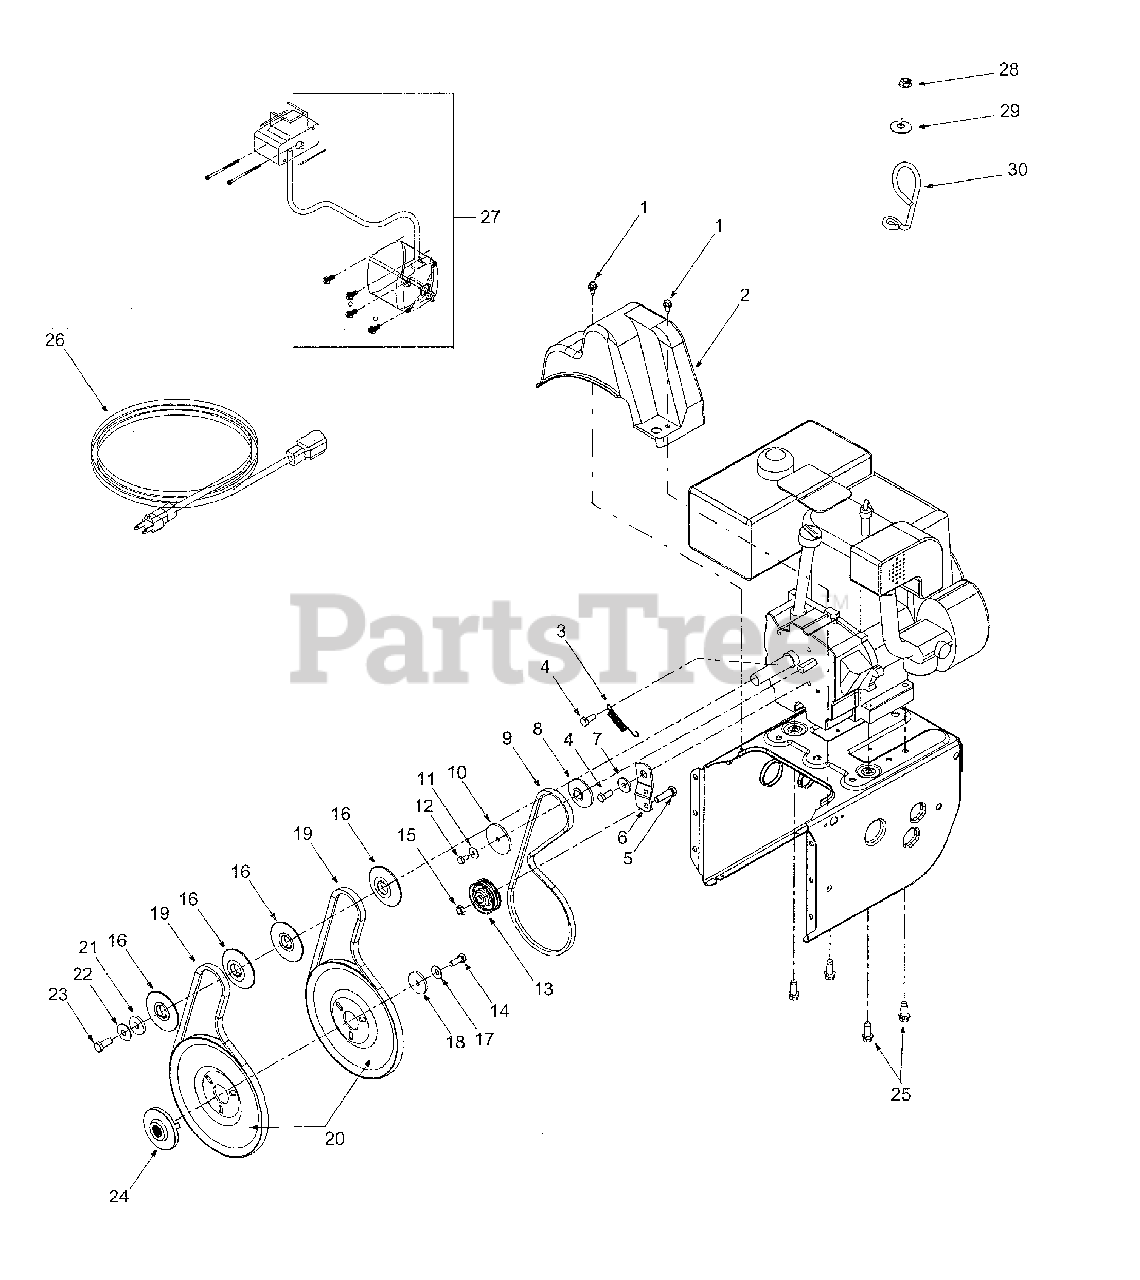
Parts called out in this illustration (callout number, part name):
1	Hex Washer Screw 1/4-20 x .625
3	Extension Spring
4	Hex Screw 5/16-24 x .75
5	Hex Cap Screw 3/8-16 x 1.25
8	Pulley Half
9	V-Belt
12	Hex Cap Screw 1/4-28 x .50
14	Lock Hex Cap Screw 5/16-24
15	Lock Jam Nut 3/8-16
19	Belt
20	Auger Pulley
21	Flat Washer 3/8 x 1.25 OD
23	Hex Cap Screw 3/8-24
24	Adapter Pulley
25	Hex Screw 3/8-16 x 1.0
26	Extension Cord
27	Electric Start Kit
28	Lock Nut, 1/4-20
29	Flat Washer, .28 x .74 x .063
